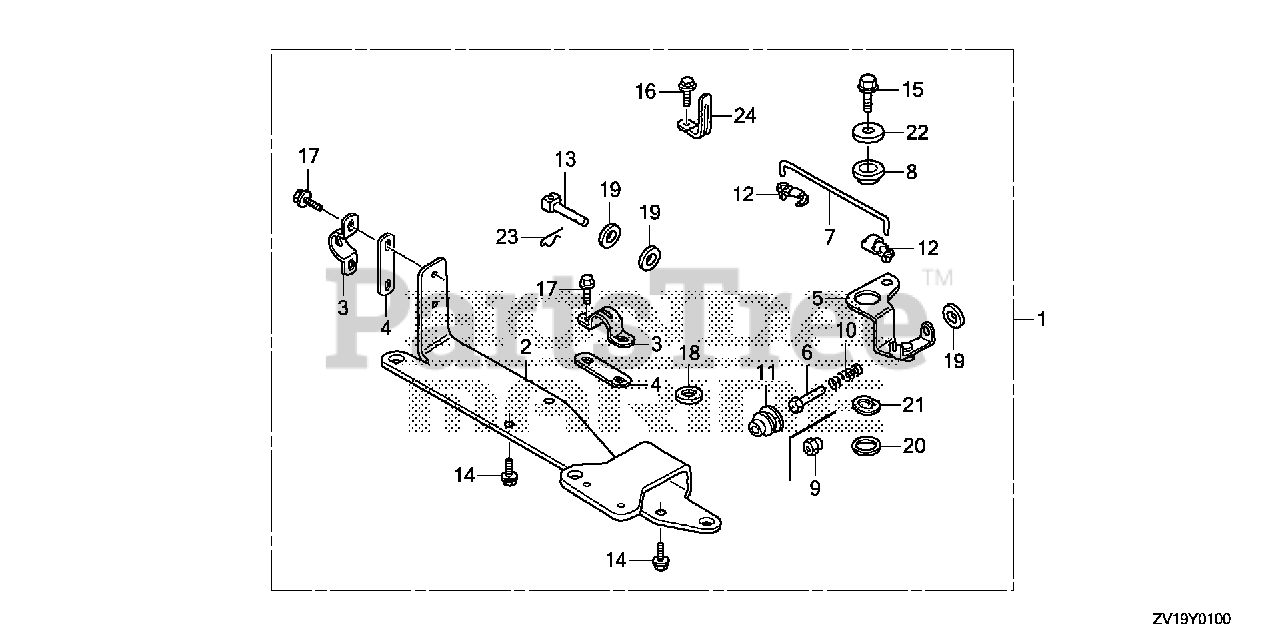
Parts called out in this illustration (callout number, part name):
1	CONTROL KIT, REMOTE
2	BRACKET, STEERING
3	CLAMP, CABLE
4	SHIM, CABLE CLAMP
5	LEVER, CONTROL
6	NUT B, CONTROL ADJUSTING
7	ROD, CONTROL
8	BUSH, CONTROL LEVER
9	NUT A, CONTROL ADJUSTING
10	SPRING, CONTROL LEVER
11	GROMMET, CONTROL CABLE
12	BUSH, LINKAGE
13	PIVOT, SHIFT
14	BOLT, FLANGE (6X14) (CT200)
15	BOLT, FLANGE (6X12) (CT200)
16	BOLT, FLANGE (5X10)
17	BOLT, FLANGE (5X10)
18	WASHER, PLAIN (22X6X1.6)
19	WASHER, PLAIN (5MM)
20	WASHER (14MM)
21	WASHER, WAVE (14MM)
22	WASHER, PLAIN (6MM)
23	PIN, LOCK (5MM)
24	CLIP B, CORD
